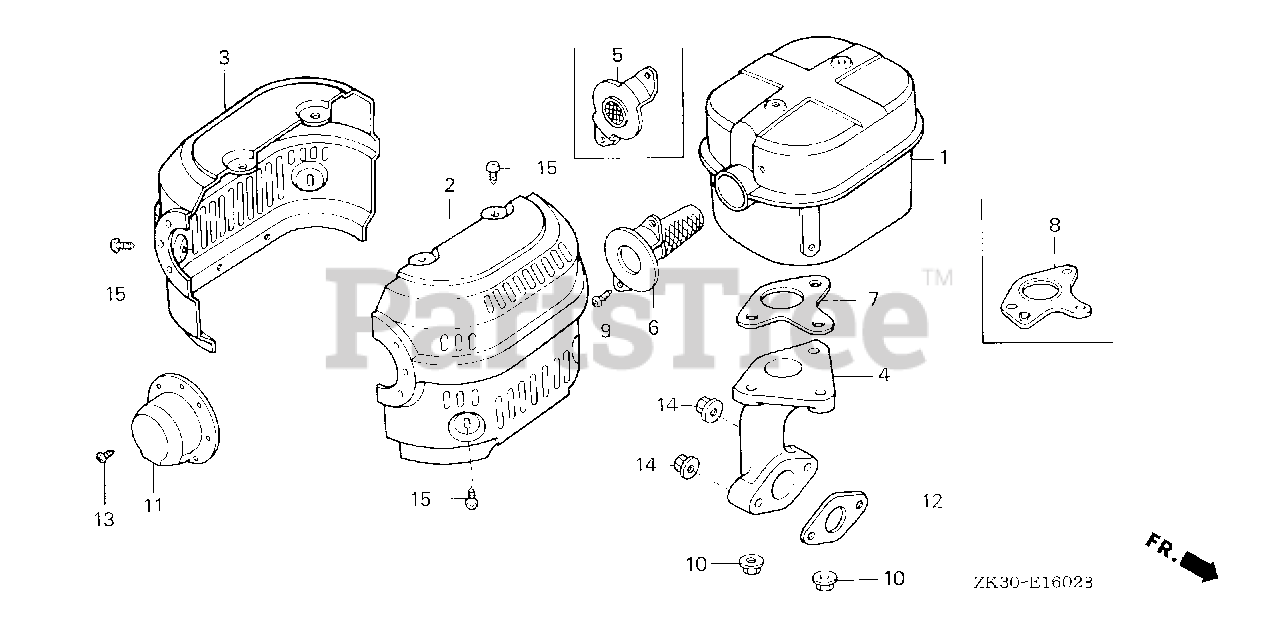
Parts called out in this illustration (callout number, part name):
2	PROTECTOR, R. MUFFLER (ALUMINIZED)
3	PROTECTOR, L. MUFFLER (ALUMINIZED)
5	FLANGE, BAFFLE
6	ARRESTER, SPARK
7	GASKET, MUFFLER (NIPPON LEAKLESS)
8	GASKET, MUFFLER (ARRESTER)
9	SCREW, TAPPING (5X8)
10	NUT, FLANGE (8MM)
12	GASKET, EX. PIPE
14	NUT, FLANGE (8MM)
15	SCREW, TAPPING (5X8)
